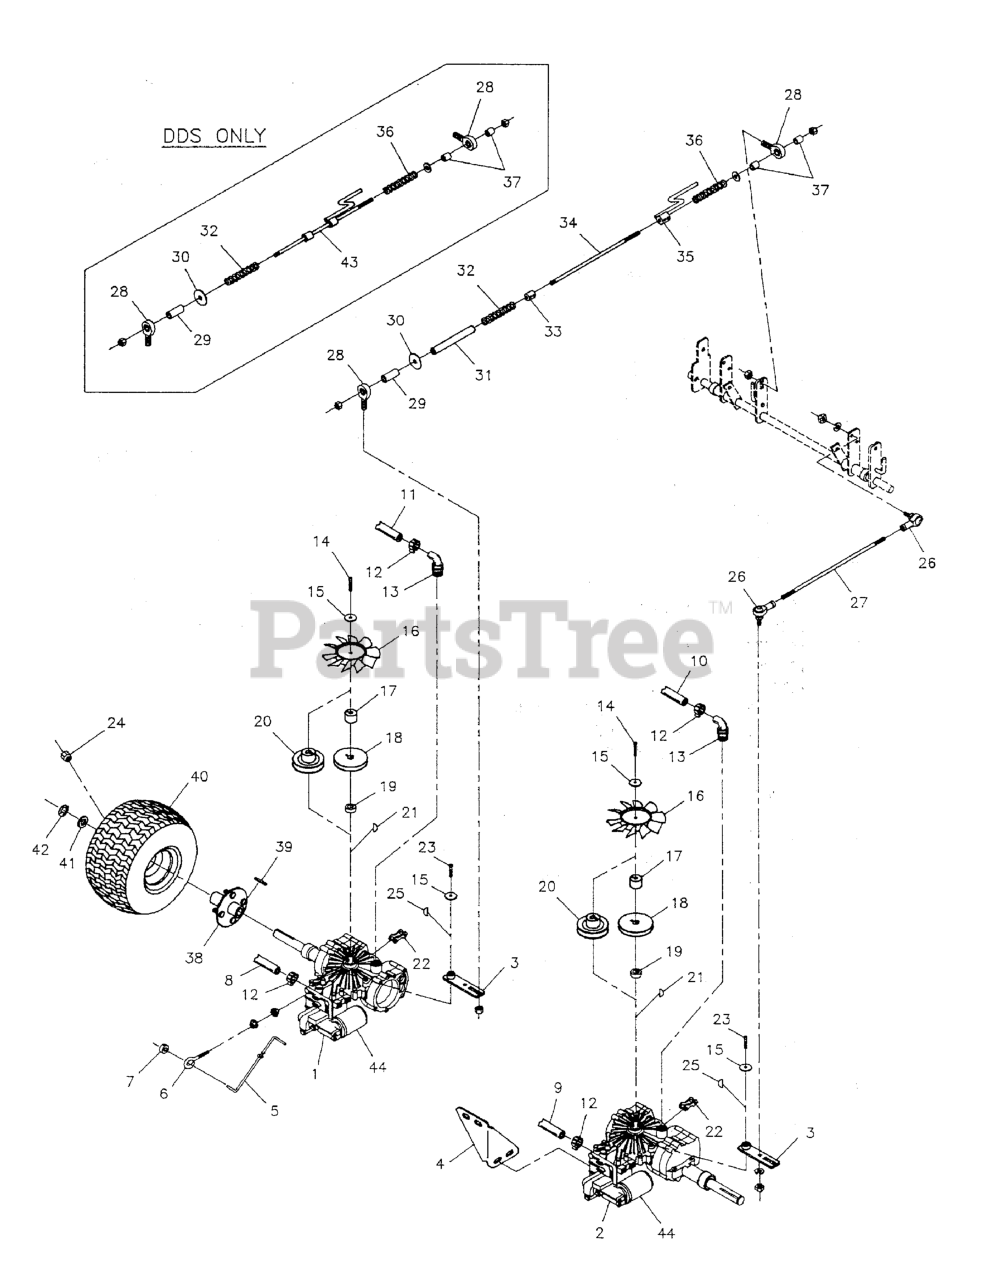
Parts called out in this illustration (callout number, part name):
1	Transmission Right Side
2	Transmission Left Side
3	Stroke Arm
4	BRACE, Transmission
5	LEVER, Dump Valve
6	EYEBOLT, 1/4-20 x 4
7	COLLAR, 5/16" Set
8	HOSE, 3/8" PUSH-LOCK, 35.00"
9	HOSE, 3/8 PUSH-LOCK, 26.00
10	HOSE, 3/8" PUSH-LOCK, 37.00"
11	HOSE, 3/8" PUSH-LOCK, 43.00"
12	CLAMP, #6 Hose
13	FITTING, 7/8" O-Ring - 3/8" Hose, 90 Degree
14	BOLT, Allen Head, 1/4-20 x 1-3/4
15	WASHER, .265 x 1.50 x .109
17	Fan Pulley Spacer
18	Pulley 17mm Bore
18	PULLEY, Transmission Input
19	SPACER, .67 x 1.25 x .50
20	PULLEY, Transmission Input
21	KEY, Hi-Pro Woodruff
22	LINK, Connecting
23	BOLT, Allen Head, 1/4-20 x 1-1/2
24	LUG NUT, 1/2-20
25	KEY, #3 Woodruff
26	BALL JOINT 5/16-24 LH FEMALE W/STUD, BR
27	ROD, Reverse
28	BALL JOINT
29	BUSHING, Brass
30	WASHER, 5/16" Fender
31	Spring Guide
32	SPRING, Compression
33	Double Set Collar
34	Control Rod
35	Anit-Rotation Weldment
36	SPRING, Compression
37	SLEEVE
39	KEY, 1/4 SQ. X 2-1/2
40	TIRE & WHEEL ASSEMBLY, 18 X 8.5 X 8
40	Tire Only
40	Rim Only
40A	WHEEL & TIRE ASSEMBLY, 18 x 7.50 x 8
41	SHIM, 1.0 X 1.5 X 0.125
42	RING, Retaining
43	ROD, Stroke Arm
44	FILTER, Transmission Oil
